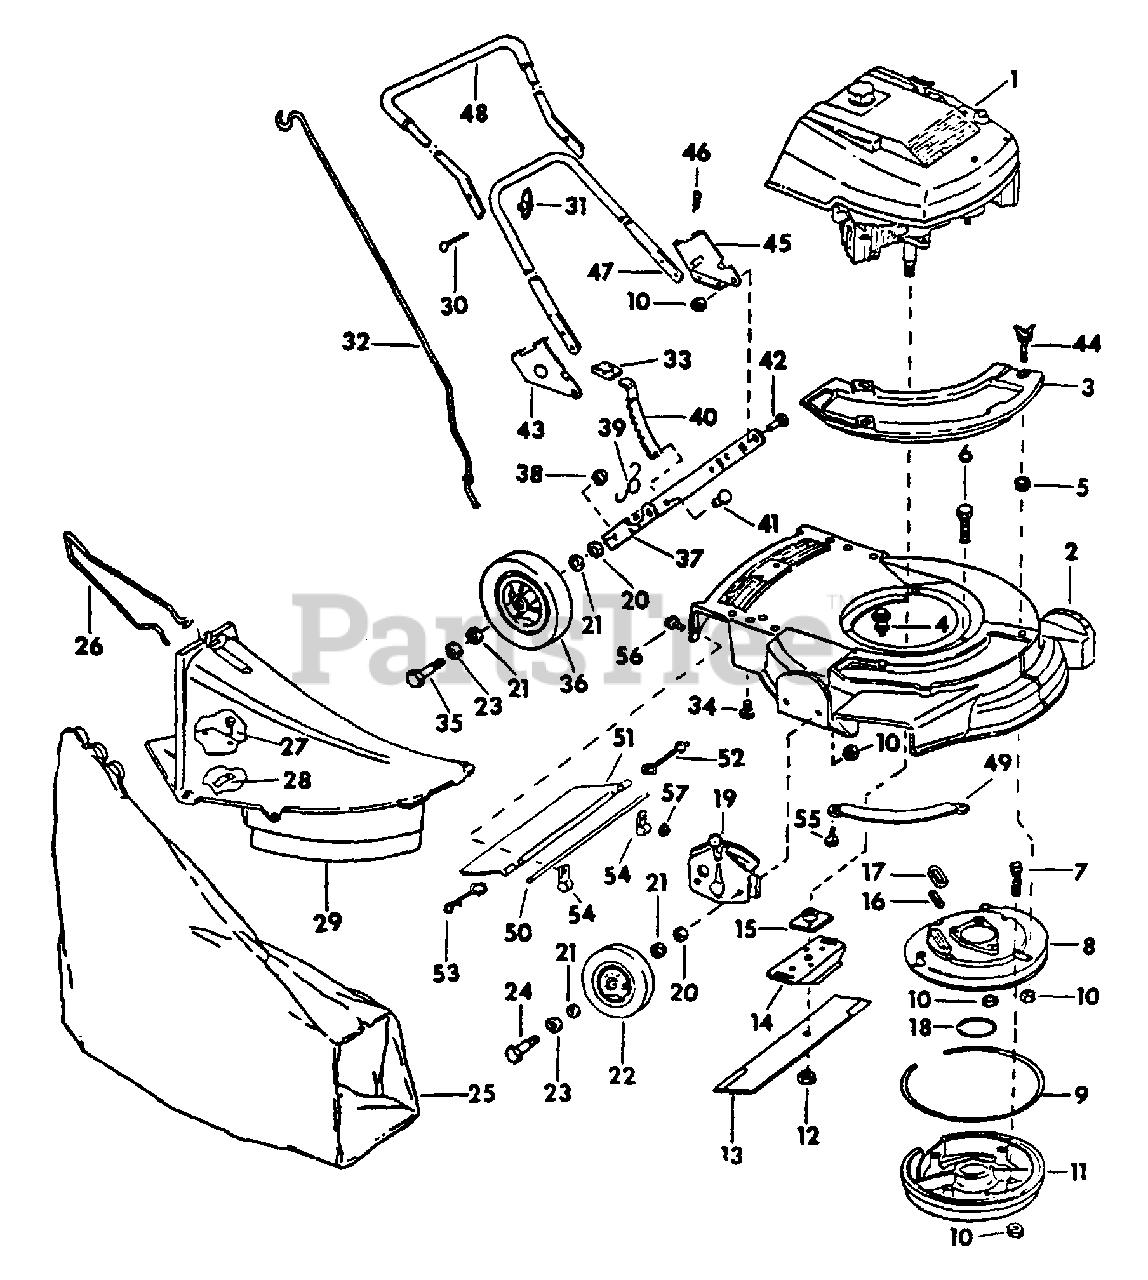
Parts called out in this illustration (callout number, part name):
1	ENGINE, IH
2	HOUSING & GROMMET ASSY, 19 IN.
3	COVER, CHUTE OPENING
4	SCREW, SHOULDER
5	NUT, GROMMET
6	SCREW, MUFFLER PLT TO HSG
7	SCREW, MUFFLER TO PLATE
8	PLATE, MUFFLER
9	GASKET, MUFFLER OUTSIDE
11	COVER, MUFFLER
13	BLADE, 19 IN.
14	STIFFENER, BLADE
15	COLLAR & PLATE
16	GASKET, EXHAUST
17	SLEEVE, EXHAUST GASKET
18	GASKET, MUFFLER INSIDE
19	ADJUSTMENT, HEIGHT
21	WASHER, FELT
22	WHEEL AND TIRE - 6 IN. FRONT
23	WASHER, WHEEL BOLT HD
24	BOLT, WHEEL FRT SHOULDER
26	GUARD, WHEEL
29	CHUTE ASSY
32	ROD, GRASS BAG
34	SCREW, HANDLE BRACKET
35	BOLT, REAR WHEEL
36	WHEEL & TIRE - 8 IN. REAR
38	NUT, REAR WHEEL BOLT
39	SPRING, HEIGHT ADJ
40	LEVER, REAR HGT ADJ
41	PIN, HEIGHT ADJ LEVER
43	BRACKET & PIN, RH
44	SCREW, WING
45	BRACKET & PIN, LH
47	HANDLE, BOTTOM
48	HANDLE & GRIP, TOP
49	BAR, TOE
52	SPRING, SHIELD LH
53	SPRING, SHIELD RH
56	SCREW, 1/4-20 X 5/8 ZND HEX-HD CAP
57	NUT, 1/4-20 HEX LOCK CAD.
